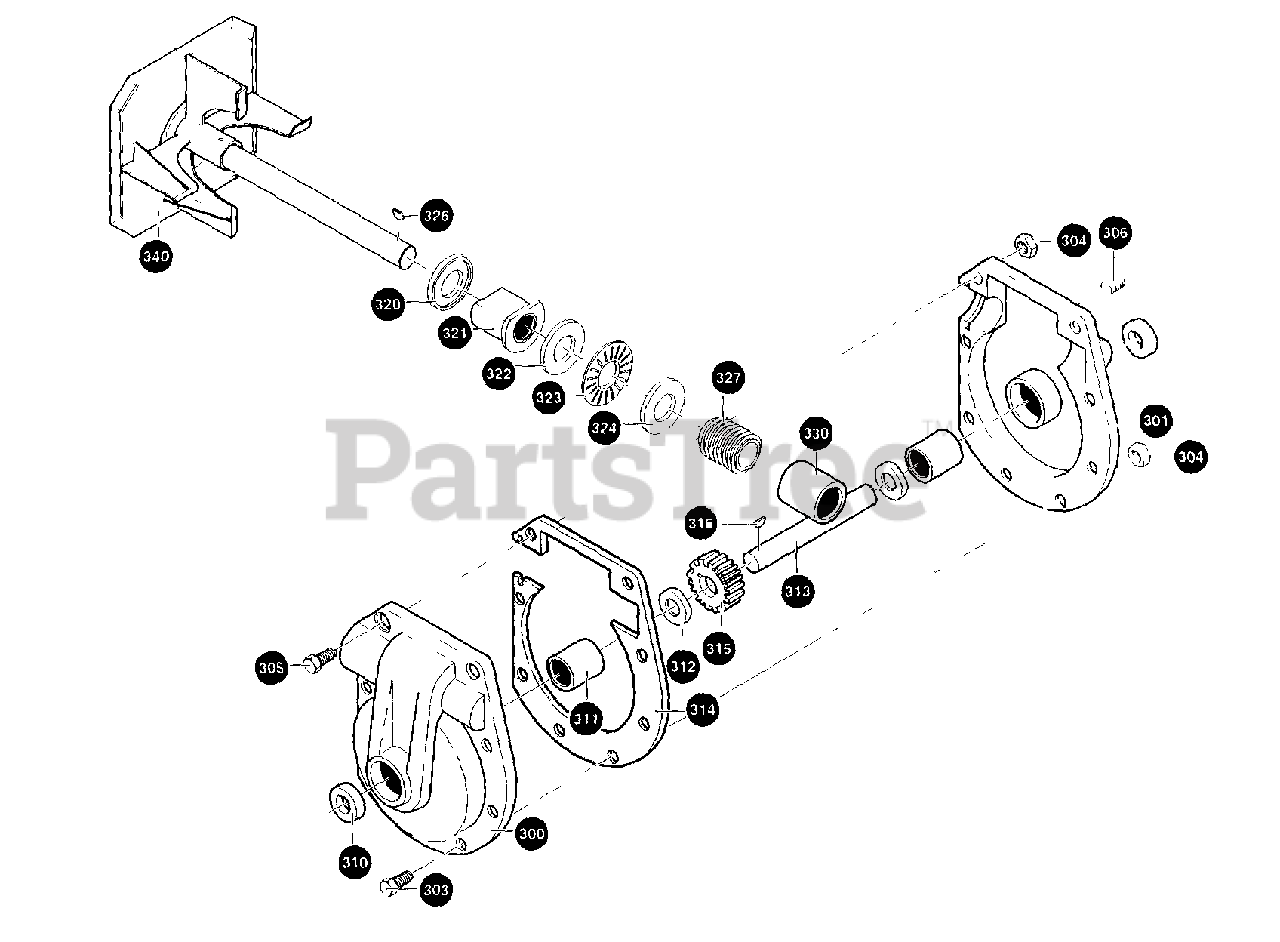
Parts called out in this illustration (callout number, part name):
300	CASE, GEAR RH
301	CASE, GEAR LH
303	SCREW, 5/16-24 X 1.00
304	NUT, 5/16-24
305	SCREW, 5/16-24 X 1.50
310	SEAL, OIL
311	BEARING, SLEEVE
312	WASHER, FLAT
313	SHAFT, AUGER
314	GASKET, GEAR BOX
320	RING, QUAD
321	BEARING, FLANGE
322	FLATWASHER .752 X 1.24 X .093
323	BRNG, ROLL
324	FLATWASHER .752 X 1.24 X .093
326	KEY, HI-PRO
330	SRNG, SLEV
340	IMPELLER, ASSY
